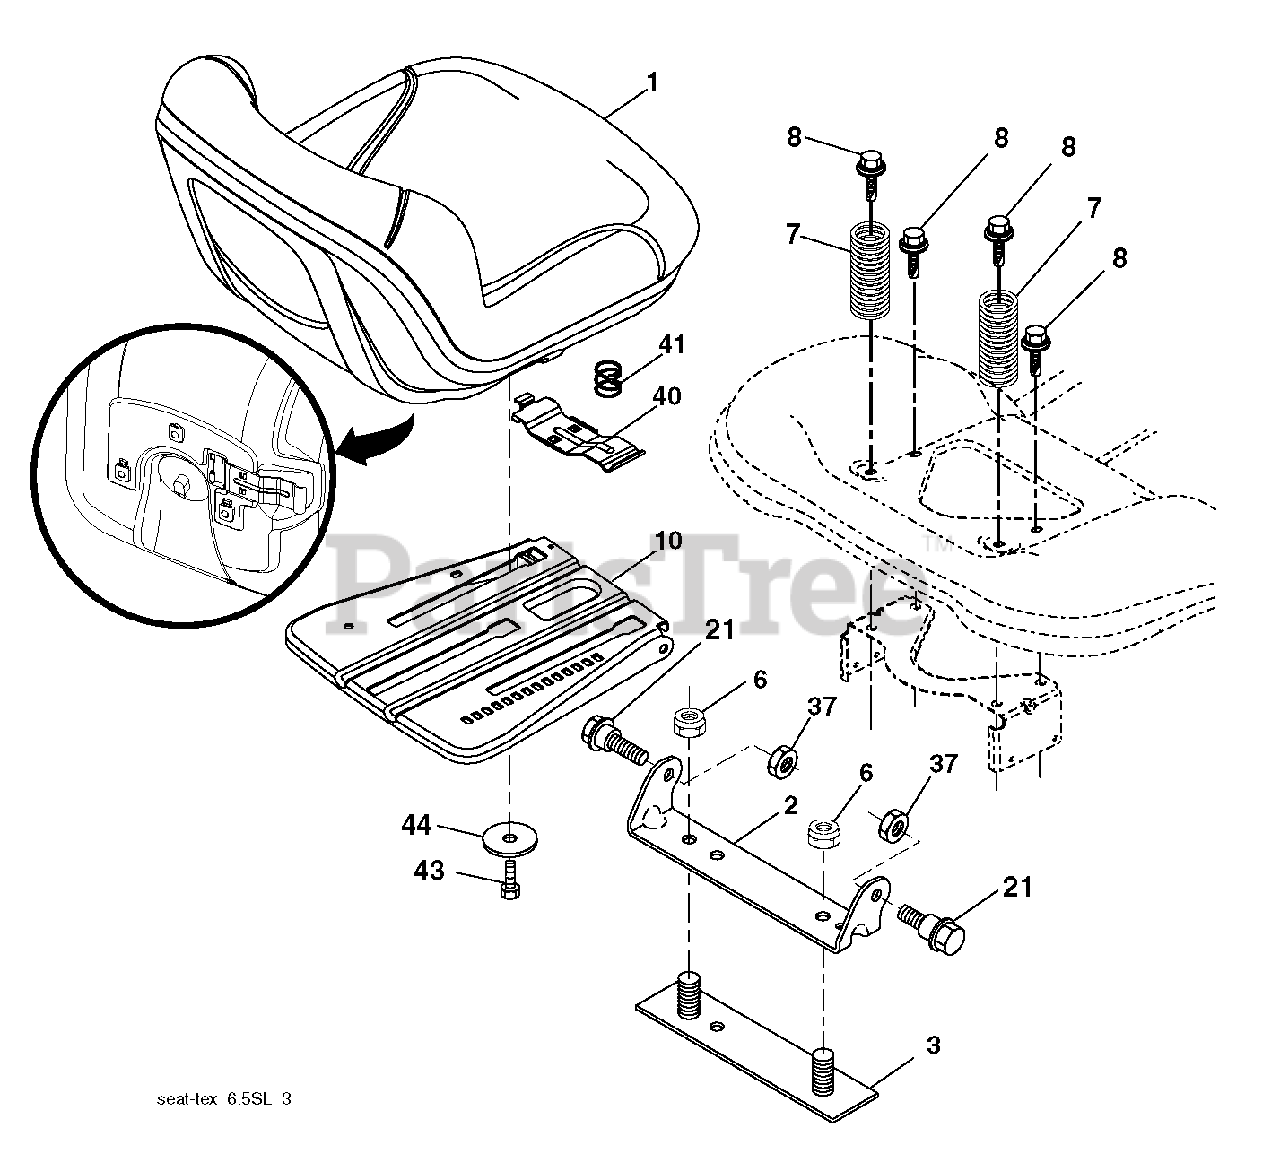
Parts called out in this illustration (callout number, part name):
1	SEAT.TH154.GREY.HUS.ARMREST
2	BRKT.PIVOT.FENDER
3	STRAP
6	NUT
7	SPRING COMPRESSION
8	BOLT, 5/16-18 X 1 3/4
10	PAN.ASM.SEAT.3PT
21	BOLT.SHOULDER.5/16-18
37	NUT.71038.31-18.HEX.NYLOCK
40	HANDLE.SLIDE.SEAT.TEX.BLACK
41	SPRING.LATCH.SEAT.TEX
44	WASHER 13/32 X 2-3/8 X 12GA
